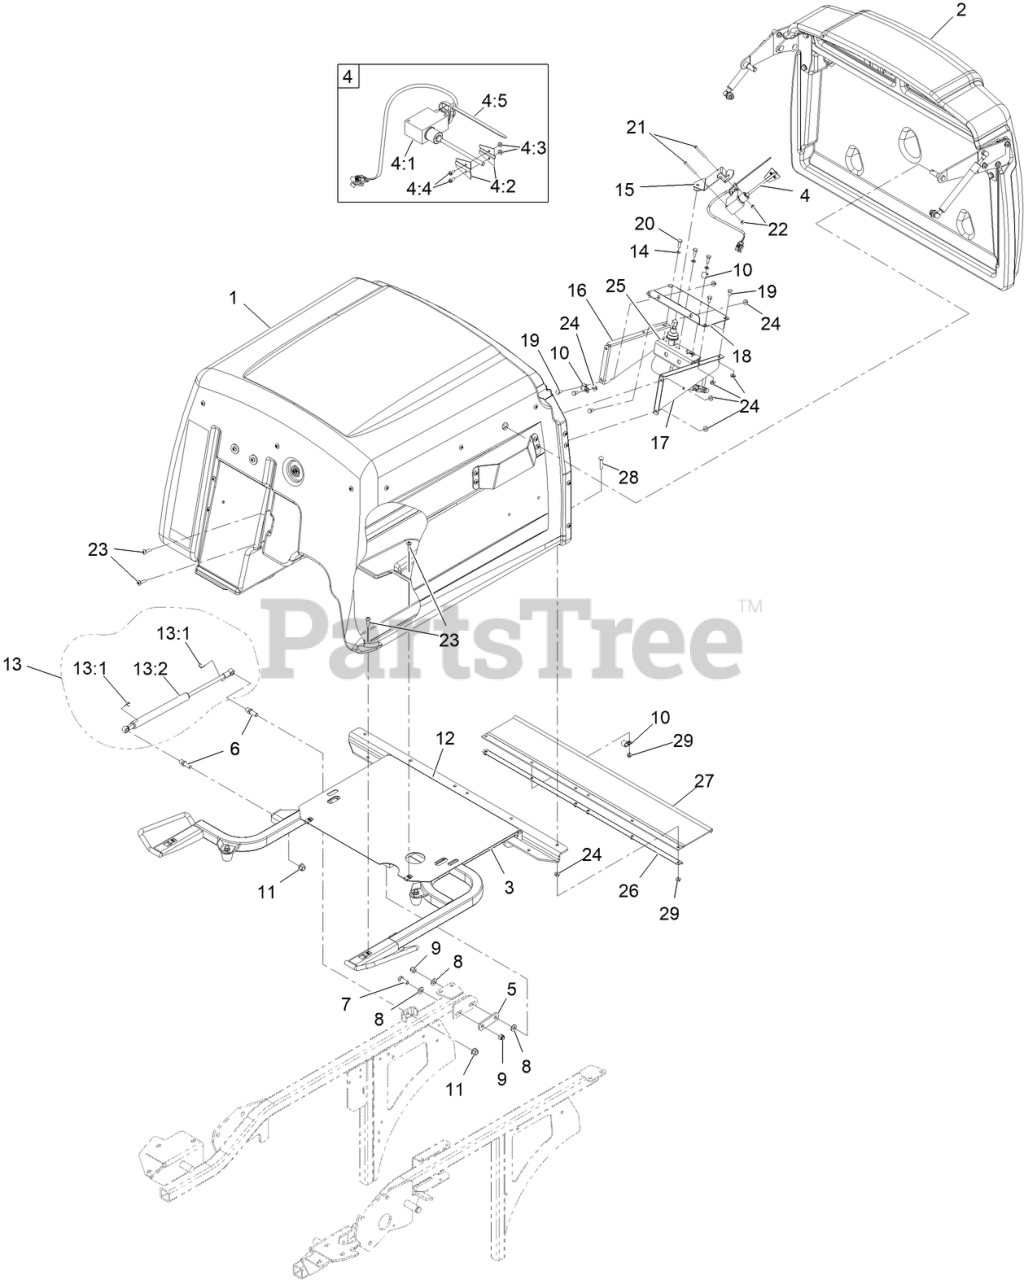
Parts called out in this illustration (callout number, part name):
1	HOPPER ASM
2	HOPPER DOOR ASM
3	HOPPER FRAME ASM
4	FILL SENSOR ASM
4:1	FILL SENSOR WIRE KIT
4:2	FLAG- SENSOR, FILL
4:3	NUT-HEX
4:4	SCREW-PAN
4:5	TIE-CABLE
5	ARM-LIFT, DECK
6	STUD-BALL
7	SCREW-HH
8	WASHER-FLAT
9	NUT-LOCK, NI
10	CLIP-LOOM
11	NUT-HF
12	SCREW-SHOULDER, HWH
13	DAMPER KIT
13:1	CLIP-RETAINER
13:2	SHOCK-COMPRESSION, GAS
14	WASHER-SPRING
15	MOUNT-SWITCH
16	BRACKET-DRIVE MOTOR, LH
17	BRACKET-DRIVE MOTOR, RH
18	PLATE-SWITCH
19	SCREW-HH
20	SCREW-HH
21	SCREW-PPH
22	NUT-LOCK, NI
23	SCREW-TTH
24	NUT-HF
25	MOTOR WIRING ASM
26	CHANNEL-FRAME, HOPPER
27	DEFLECTOR-GRASS
28	SCREW-CARR
29	NUT-HF
